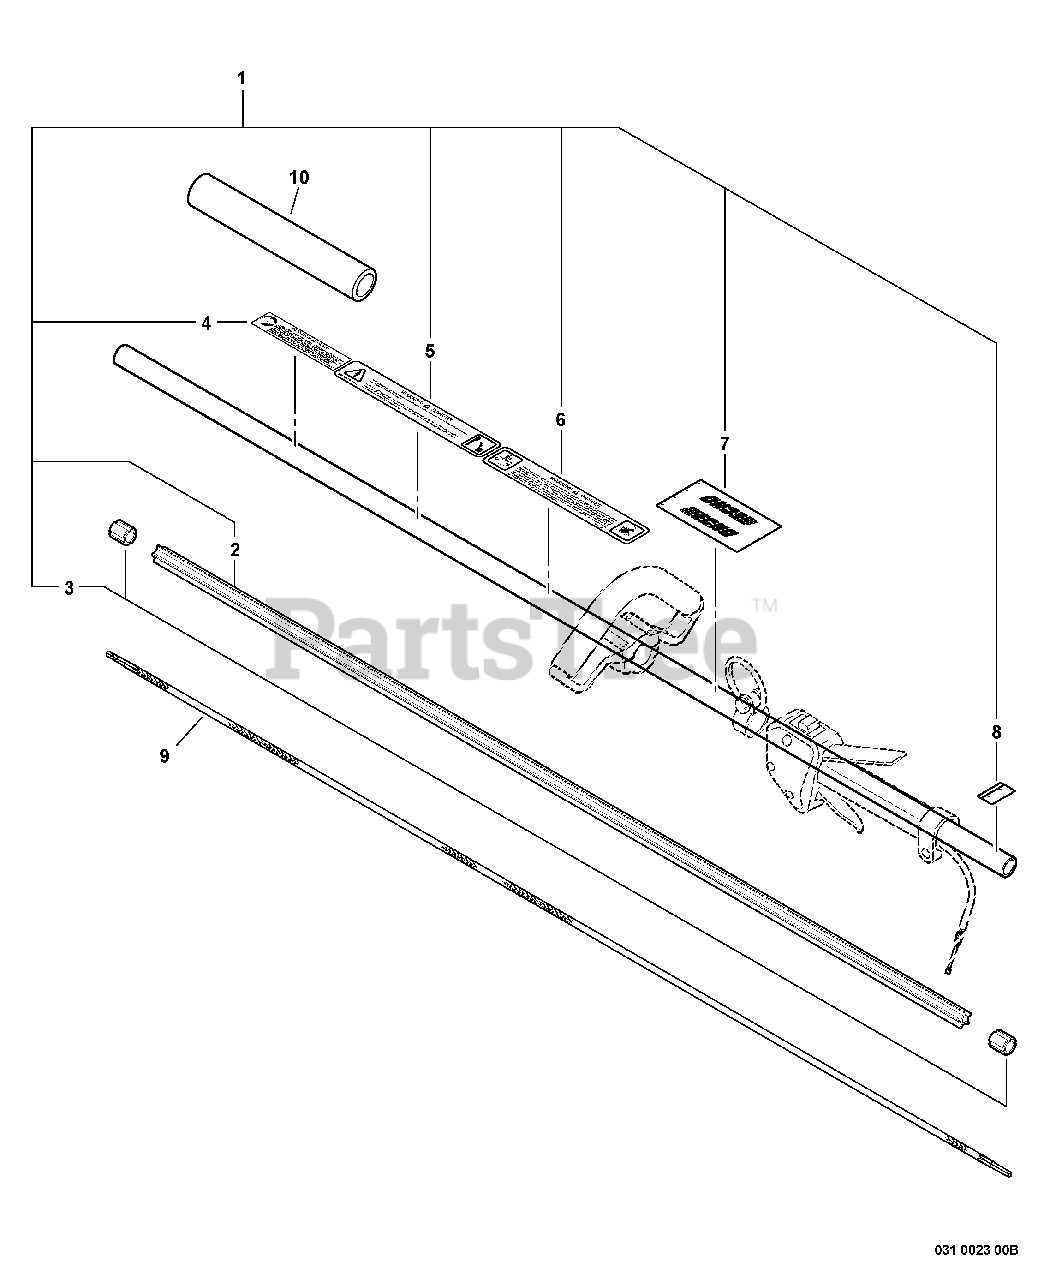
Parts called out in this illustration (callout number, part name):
1	MAIN PIPE ASSY
2	LINER - FLEXIBLE
4	LABEL, CAUTION
5	LABEL - CAUTION
6	LABEL, CAUTION
7	LABEL, HANDLE LOCATION
8	LABEL - ALIGNMENT
9	DRIVESHAFT - FLEXIBLE
10	GRIP, HANDLE
